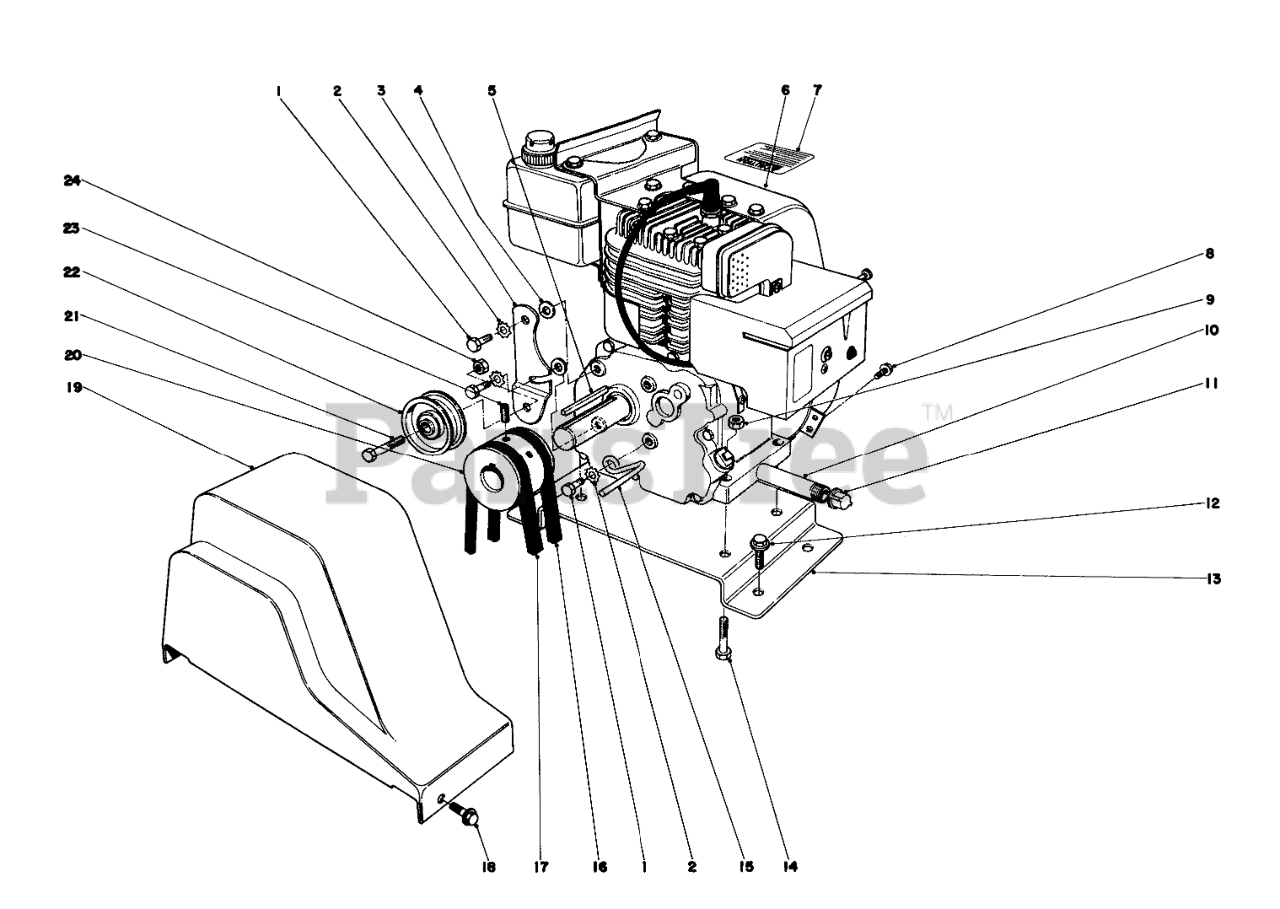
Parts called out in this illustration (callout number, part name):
1	SCREW-HH
2	WASHER-LOCK
3	ENGINE IDLER ARM
4	WASHER-PLAIN
6	Engine
7	Decal Instruction
8	SCREW
9	NUT-LOCK, CONE
10	NIPPLE-PIPE
11	CAP-PIPE
12	SCREW-HHFTF
13	ENG MTG PLATE R
14	SCREW-HH
15	BELT RETAINER
16	V-BELT
17	V-Belt
18	SCREW-HWH
19	BELT GUARD
20	Pulley
21	SCREW-HH
22	PULLEY-IDLER
23	Screw-Set
24	NUT-HEX
